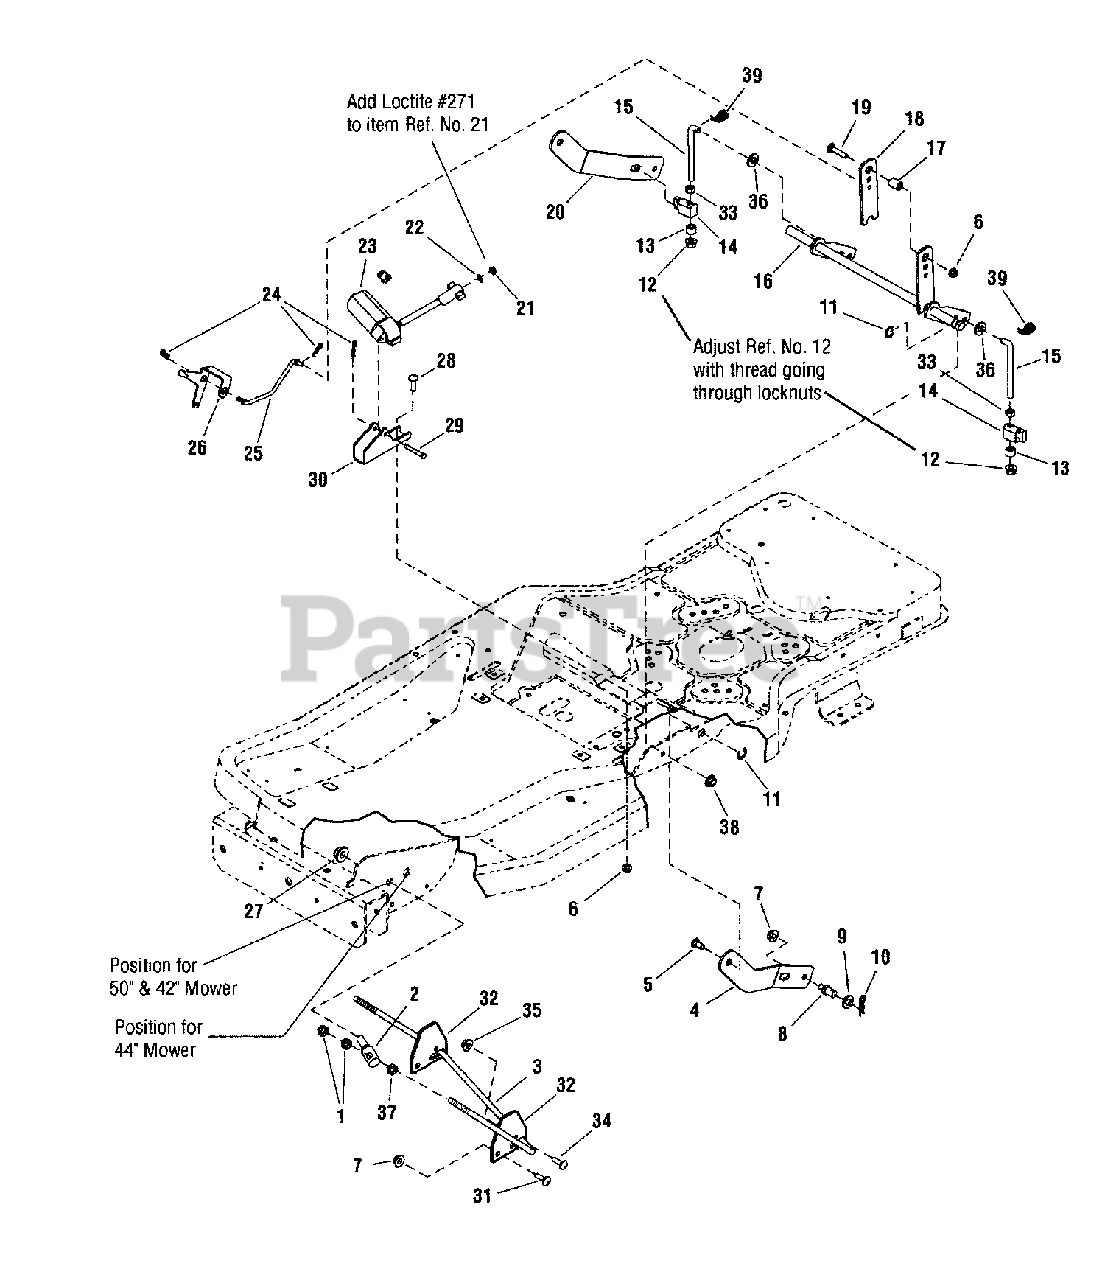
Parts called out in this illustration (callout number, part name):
1	NUT, 7/16-14 Hex Jam
2	TRUNNION, 1/2-13 Thread
3	ROD, Bail (7/16-14 Thread, 2 Places)
4	ARM, Mower Lift L.H.
5	SHOULDER BOLT, 5/16-18
6	NUT, 5/16-18 Hex Flange Lock, Small - Black
7	NUT, 3/8-16 Hex Center Lock Jam
8	PIN, 3/8-16 Threaded Shoulder
9	WASHER, 1/2" Flat (0.51 I.D. x 1.00 O.D. x .10 Thick)
10	CLIP, Hair Pin .093 Dia.
11	RING, External (Klipring) for .625 Dia. Shaft
12	NUT, 3/8-16 Hex Flange Nyloc
13	SPACER, .385 I.D. x .6697 O.D. x .455 Long, Powdered Metal
14	TRUNNION, Powdered Metal
15	ROD, Mower Lift, 3/8-16 Thread
16	WELDMENT, Lift Shaft
17	SPACER, .328 I.D. x .625 O.D. x .781 Long (Powdered metal)
18	ARM, Lift Trunnion
19	BOLT, 5/16-18 x 1-1/2" Round Head Short Square Neck, GR5
20	ARM, Mower Lift R.H.
21	NUT, 1/4-20 Hex, L.H. Thread
22	WASHER, 1/4" Flat (.27 I.D. x .62 O.D.)
23	MOTOR, Mini-Actuator (Electric)
24	HAIR PIN
25	ROD, Height-of-Cut Indicator
26	INDICATOR, Height-of-Cut
27	NUT, HEX FLANGE 1/2-13 Hex Flange Two Way Lock
28	BOLT, Carriage, Short Neck, 5/16-18 x 1
29	PIN, Shear
30	BRACKET, Electric Motor Mount
31	BOLT, Carriage, Short Square Neck, 3/8-16X0.750 GR5, Black
32	PLATE, Pivot Lock
33	NUT, HEX 3/8-16 Hex
34	BOLT, 1/4-20 x 2" Round Head Short Square Neck, GR5, Black
35	NUT, 1/4-20 Hex Flange Lock
36	WASHER, .375 Flat (.41 I.D. x .87 O.D.)
37	NUT, 7/16-14 Hex
38	NUT, 5/16-18 Top Lock, GR B
39	COTTER PIN, 3/8" Self-Locking, YZ
